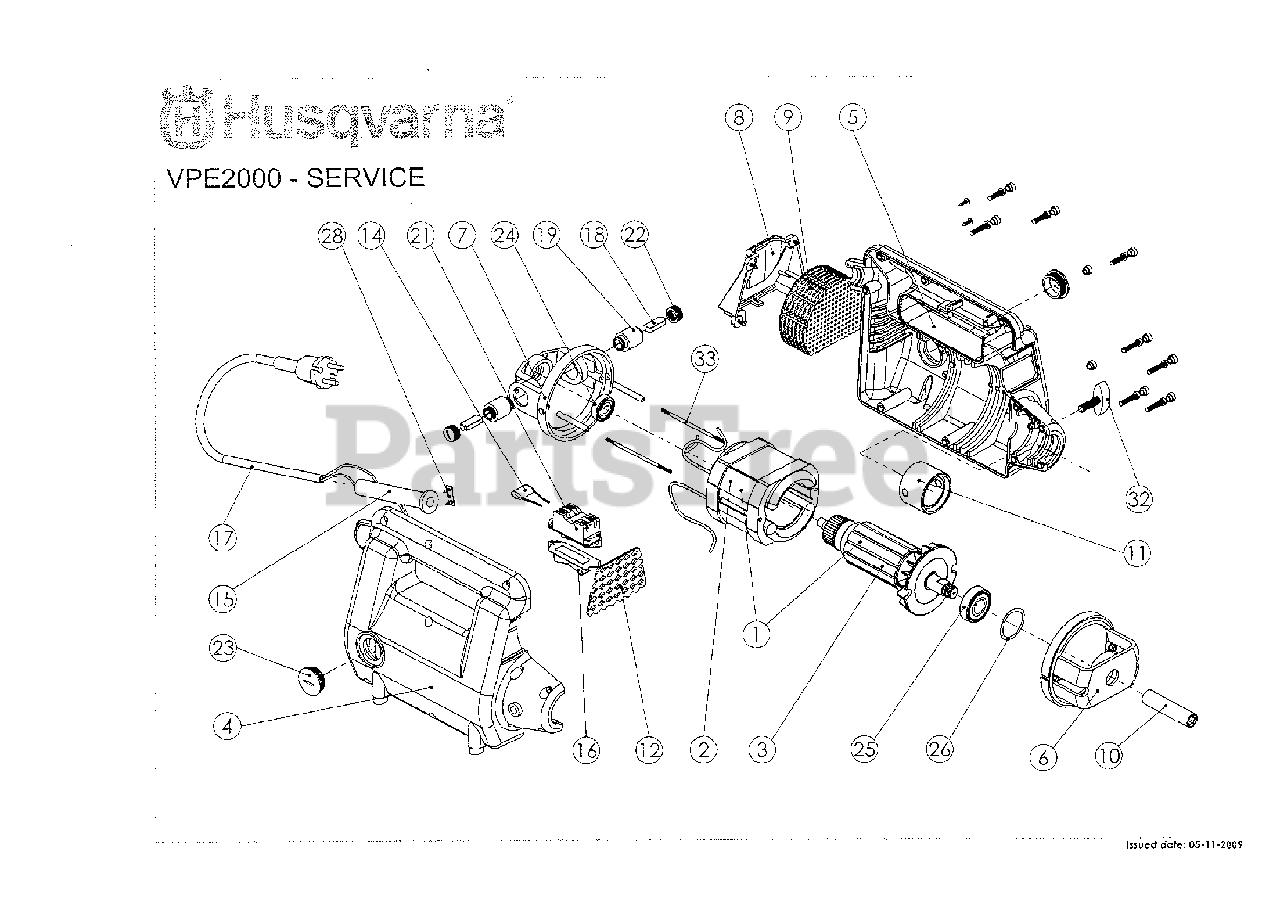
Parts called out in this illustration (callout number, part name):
1	ENSEMBLE MOTOR UNIVERS./
11	DOUILLE POUR FIXATION/FLEXIBLE
14	CROSS-PIECE ISOLATING/
16	PROTECTEUR PLASTIC DE/L'SWITCH
17	CORDON D'ALIMENTATION/
23	OBTURATEUR PORTE CHARBON/
24	ROULEMENT A BILLES/6200 ZZ
25	ROULEMENT A BILLES/6203 ZZ
29	OTHER PRODUCTION COMPONENT
32	VIS CYLINDRIQUE FIXATION/MANCH
33	VIS CYLINDRIQUE FIXATION/MANCH
